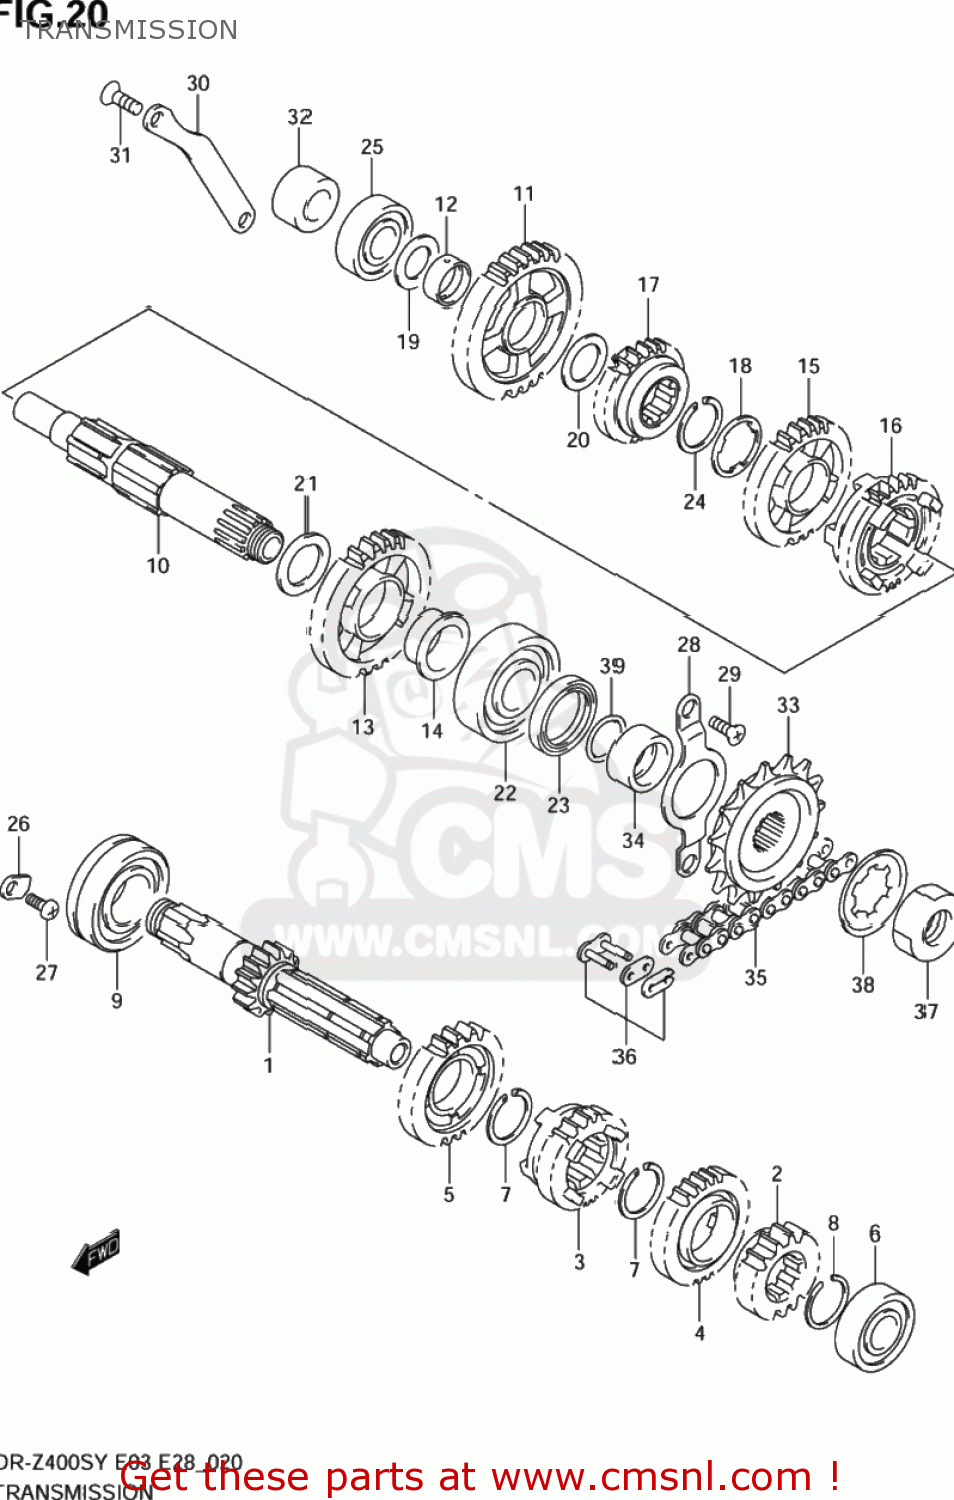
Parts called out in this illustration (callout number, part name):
1	SHAFT,COUNTER(NT:14)
2	GEAR,2ND DRIVE(NT:15)
3	GEAR,3RD DRIVE(NT:16)
4	GEAR,4TH DRIVE(NT:22)
5	GEAR,5TH DRIVE(NT:22)
6	BEARING(17X40X12)
7	CIRCLIP
8	CIRCLIP
9	BEARING(25X52X15)
10	SHAFT,DRIVE
11	GEAR,1ST DRIVEN(NT:32)
12	BUSH,1ST DRIVEN GEAR
13	GEAR,2ND DRIVEN(NT:26)
14	BUSH,2ND DRIVEN GEAR
15	GEAR,3RD DRIVEN(NT:22)
16	GEAR,4TH DRIVEN(NT:24)
17	GEAR,5TH DRIVEN(NT:19)
18	WASHER,LOCK
19	SHIM(17X30X1)
20	SHIM(20X30X1)
21	SHIM(22X34X1)
22	BEARING(22X56X16)
23	SEAL,OIL(30X40X6)
24	CIRCLIP
25	BEARING(17X40X12)
26	RETAINER
27	BOLT(6X12)
28	RETAINER,DRIVE SHAFT OIL SEAL
29	SCREW(6X14)
30	RETAINER,KICK IDLE GEAR
31	SCREW ,6X16
32	SPACER(17X30.5X16.3)
33	SPROCKET,ENGINE(15T)
34	SPACER,ENGINE SPROCKET
35	CHAIN ASSEMBLY,DRIVE RK520
36	JOINT SET,CHAIN
37	NUT
38	WASHER,LOCK
39	O RING(D:2.5,ID:21)
